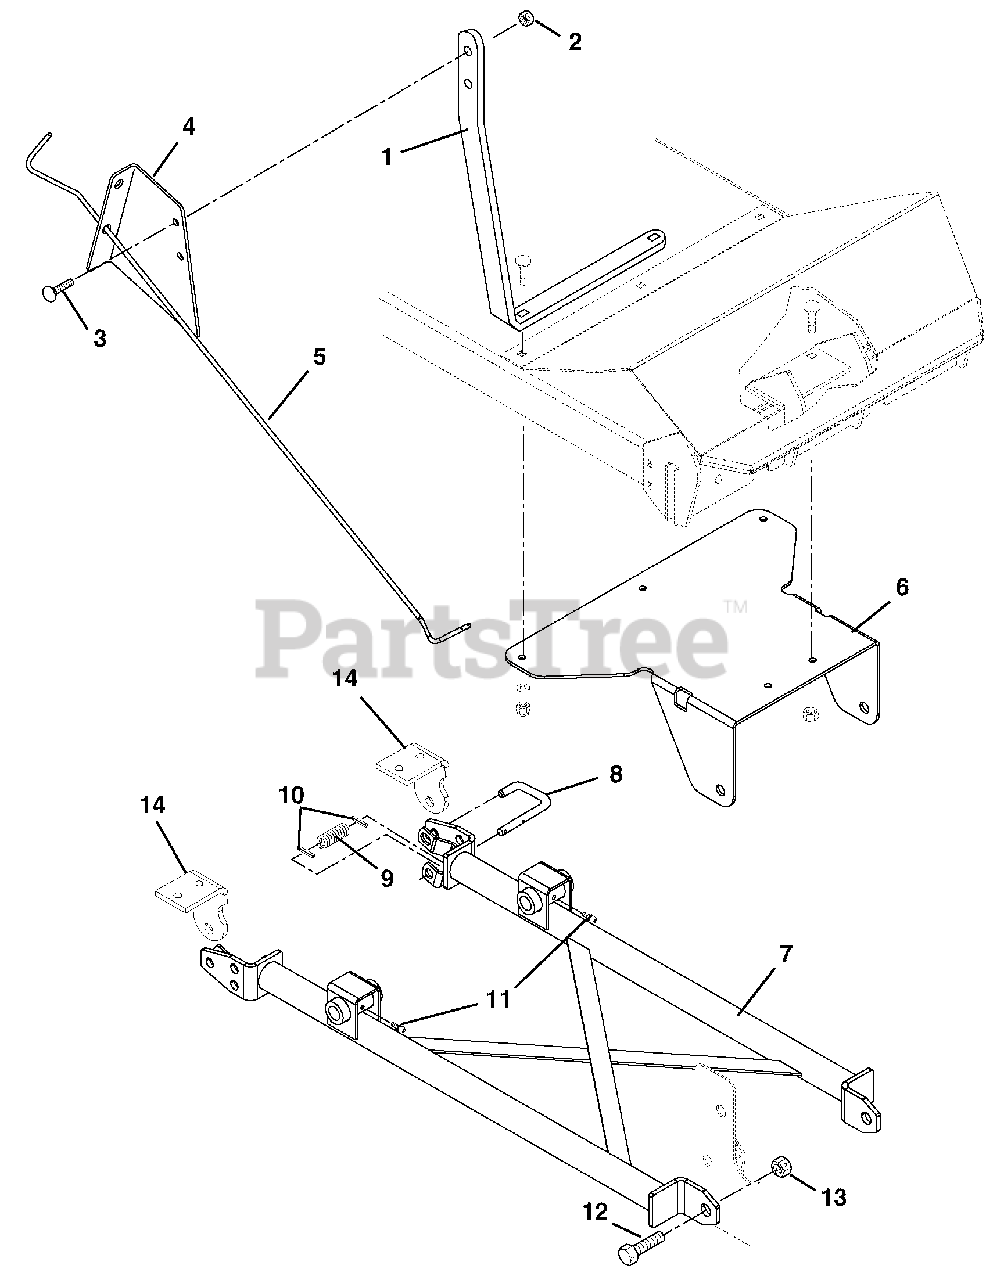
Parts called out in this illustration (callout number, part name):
1	CONTROL SUPPORT
2	@NUT-LK-CTR .38-16 YWZC
3	@BLT-RDHDSHSQNK.38-16X1.0 G5YZ
4	CONTROL BRACKET
5	ROD, CONTROL
6	HANGER BRACKET
7	SUPPORT WELDMENT
8	LATCH PIN
9	SPRG, COMP .058X.65X2.13 WLD15
10	PIN-ROLL .125X.75
11	FTG-LUBE .25-28X.256 YWZC
12	@BLT-HEX .62-11X1.50 GR5 YWZC
13	@NUT-LK-CTR .62-11 YWZC
14	REAR HANGER
